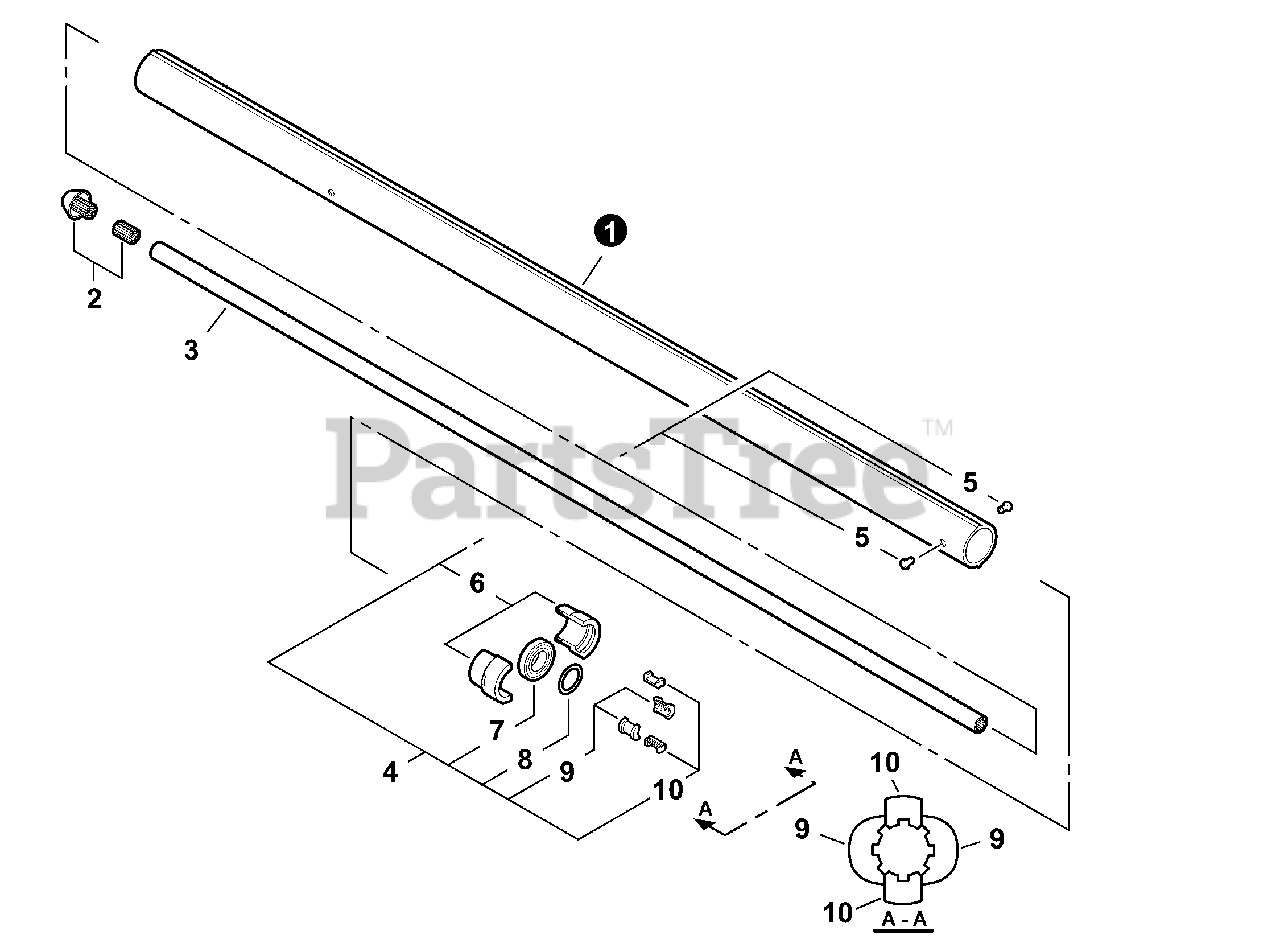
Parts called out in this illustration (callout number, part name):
1	PIPE, MAIN - BLACK
2	ADAPTER, UPPER DRIVE SHAFT
3	SHAFT, UPPER DRIVE L= 79.75
4	HOLDER ASSY, BEARING
6	HOLDER, BEARING
7	BEARING, BALL 6002 DDU
8	WASHER, WAVE
9	GUIDE, SHAFT - LARGE
10	GUIDE, SHAFT - SMALL
